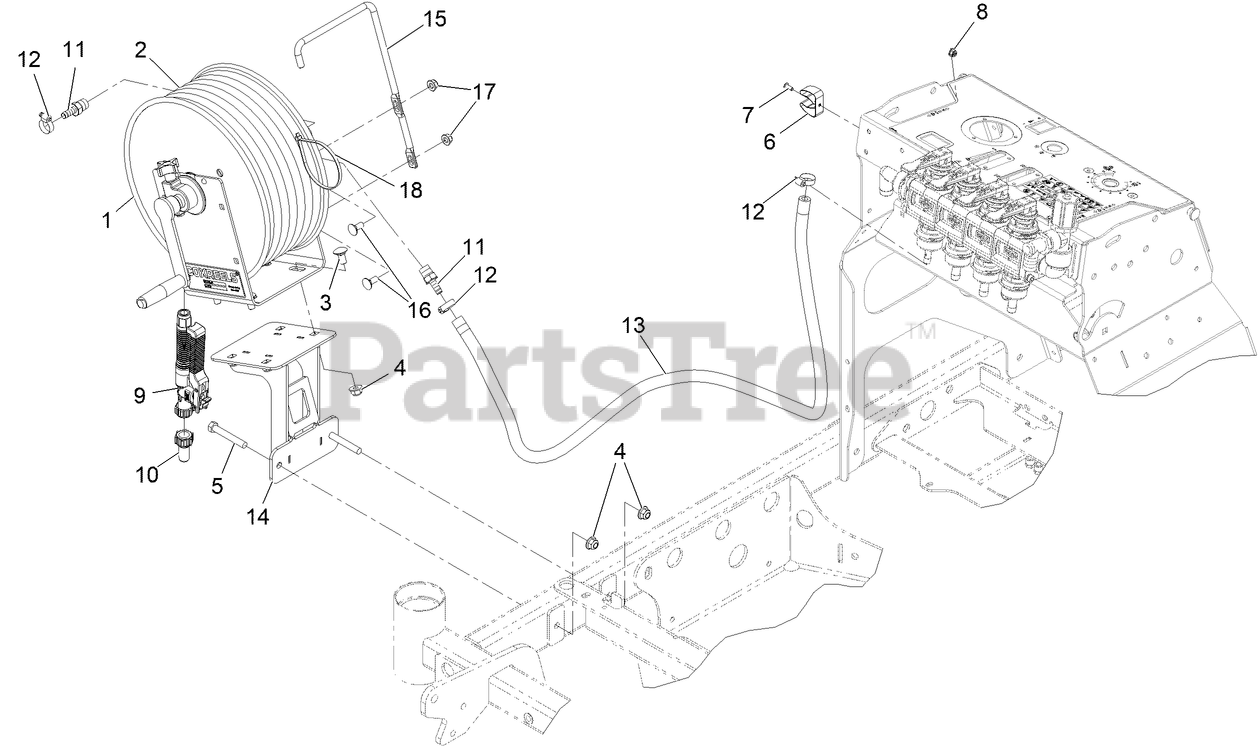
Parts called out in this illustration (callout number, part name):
1	REEL-HOSE
2	HOSE-SPRAY, 75'
3	SCREW-CARRIAGE
4	Nut-Hex Flange
5	HHCS,3/8-16X2-1/2,ST/ST 18-8
6	Holder-Tool, Clip
7	Screw-HSBH
8	Nut-Hex Flange
9	GUN-SPRAY, SPOT
10	TIP-SPRAY, #12 SPOT
11	FITTING,MALE
12	CLAMP-HOSE
13	HOSE-SPRAY
14	ASM-REEL MOUNT
15	GUIDE-HOSE, REEL
16	SCREW-CARR
17	Nut-Hex Flange
18	TIE-CABLE
